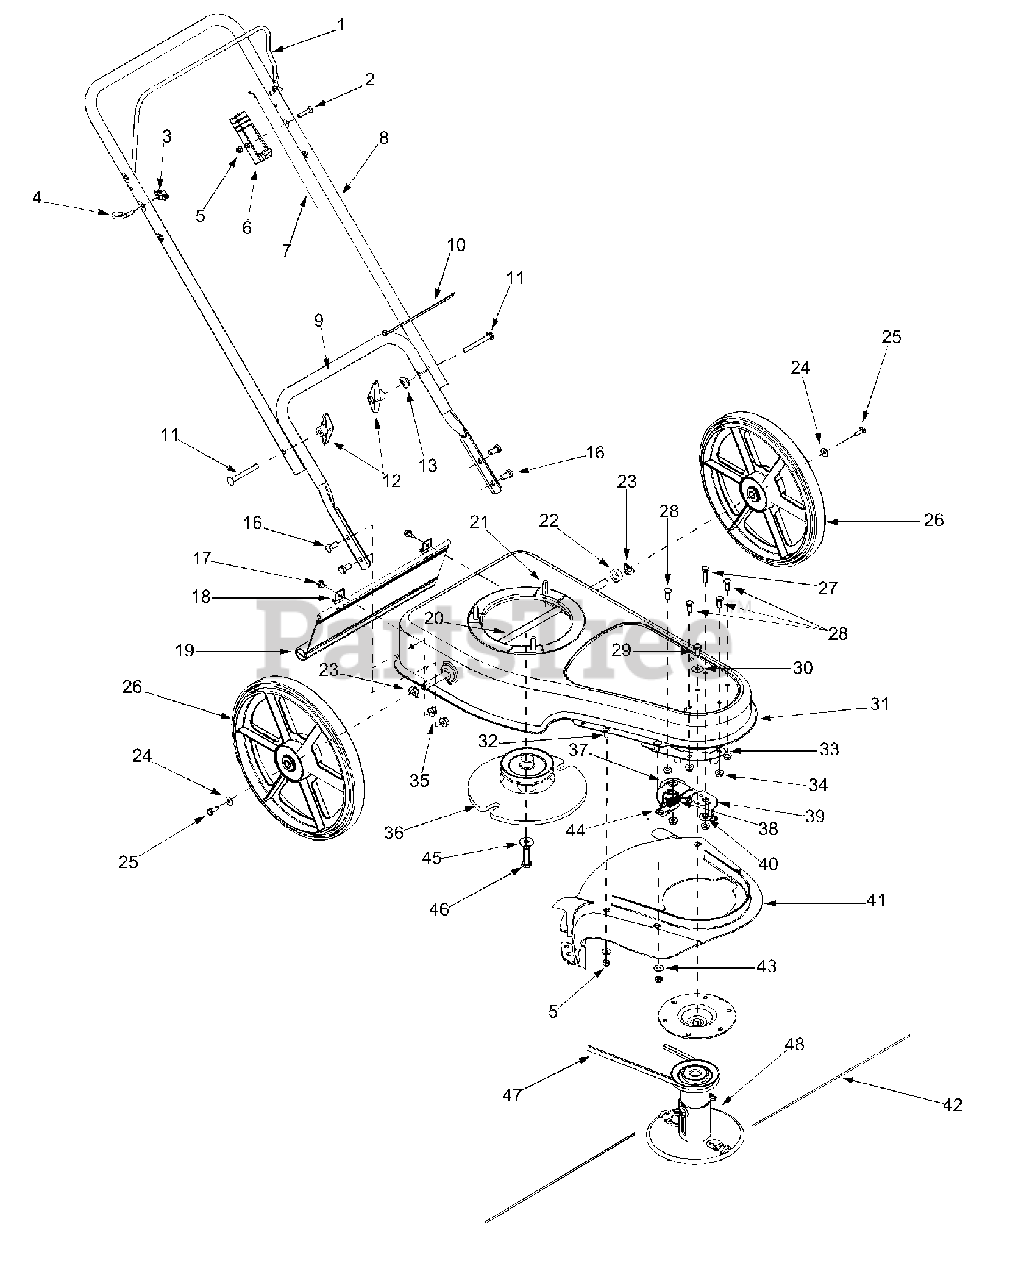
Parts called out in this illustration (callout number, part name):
3	Knob 1/4-20
4	Eye Bolt 1/4-20
5	Hex Lock Nut
6	Throttle Housing
7	Throttle Cable
11	Carriage Screw 5/16-18 x 2.0
12	Wing Nut 5/16-18
13	Saddle Washer .320 ID x .93 OD
16	Hex Cap Screw 3/8-16 x .750
17	Hex Washer Screw 1/4-14 x .625
18	Trail Shield Clip
19	Trail Shield
20	Axle Assembly
21	Hex Washer Screw 3/8-16 x .250
22	Spacer .51 ID x 1.00 OD x .38
23	Spacer Washer .50 ID x 1.0 OD
24	Bell Washer .265 ID x .75 OD
25	Hex Cap Screw 1/4-20 x .75
26	Wheel 14 x 1.8
27	Screw 5/16-18 x 1.25
28	Screw 5/16-18 x .75
29	Hex Cap Screw 5/16-24 x .625
30	Bell Washer .325 ID x .930 OD
34	Flange Lock Nut 5/16-18
35	Flange L-Nut 3/8-16
36	Flywheel Pulley
37	Idler Pulley
38	Extension Spring .50 ID x 3.375
39	Idler Bracket Assembly
40	Idler Spacer
41	Trimmer Deflector Assembly
42	Trimmer Line .130 Dia
43	Flat Washer .28 ID x .74 OD
45	Bell Washer .396 ID x 1.140 OD
46	Hex Cap Screw 3/8-24 x 1.50
47	V-Belt
48	Spindle Assembly, includes 782-0143
